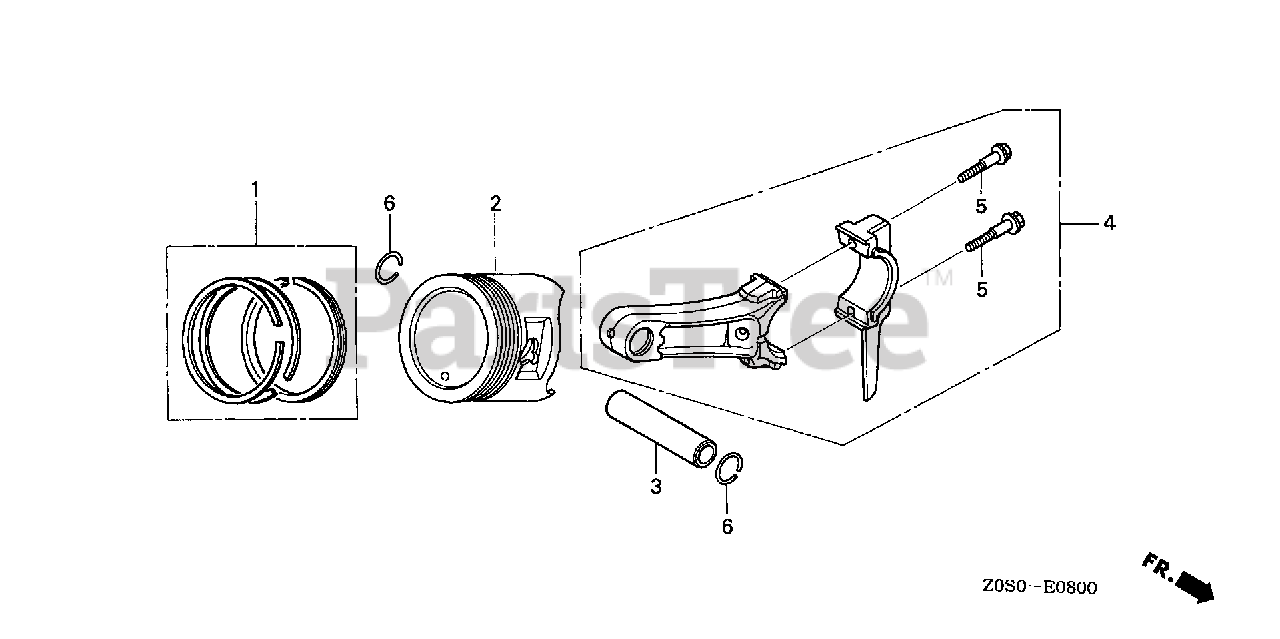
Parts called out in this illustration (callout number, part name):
1	RING SET, PISTON (STD) (RIKEN)
1	RING SET, PISTON (0.25) (RIKEN)
1	RING SET, PISTON (0.50) (RIKEN)
1	RING SET, PISTON (0.75) (RIKEN)
2	PISTON (STD)
2	PISTON (0.25)
2	PISTON (0.50)
2	PISTON (0.75)
3	PIN, PISTON
4	ROD ASSY., CONNECTING
5	BOLT, CONNECTING ROD
6	CLIP, PISTON PIN (13MM)
